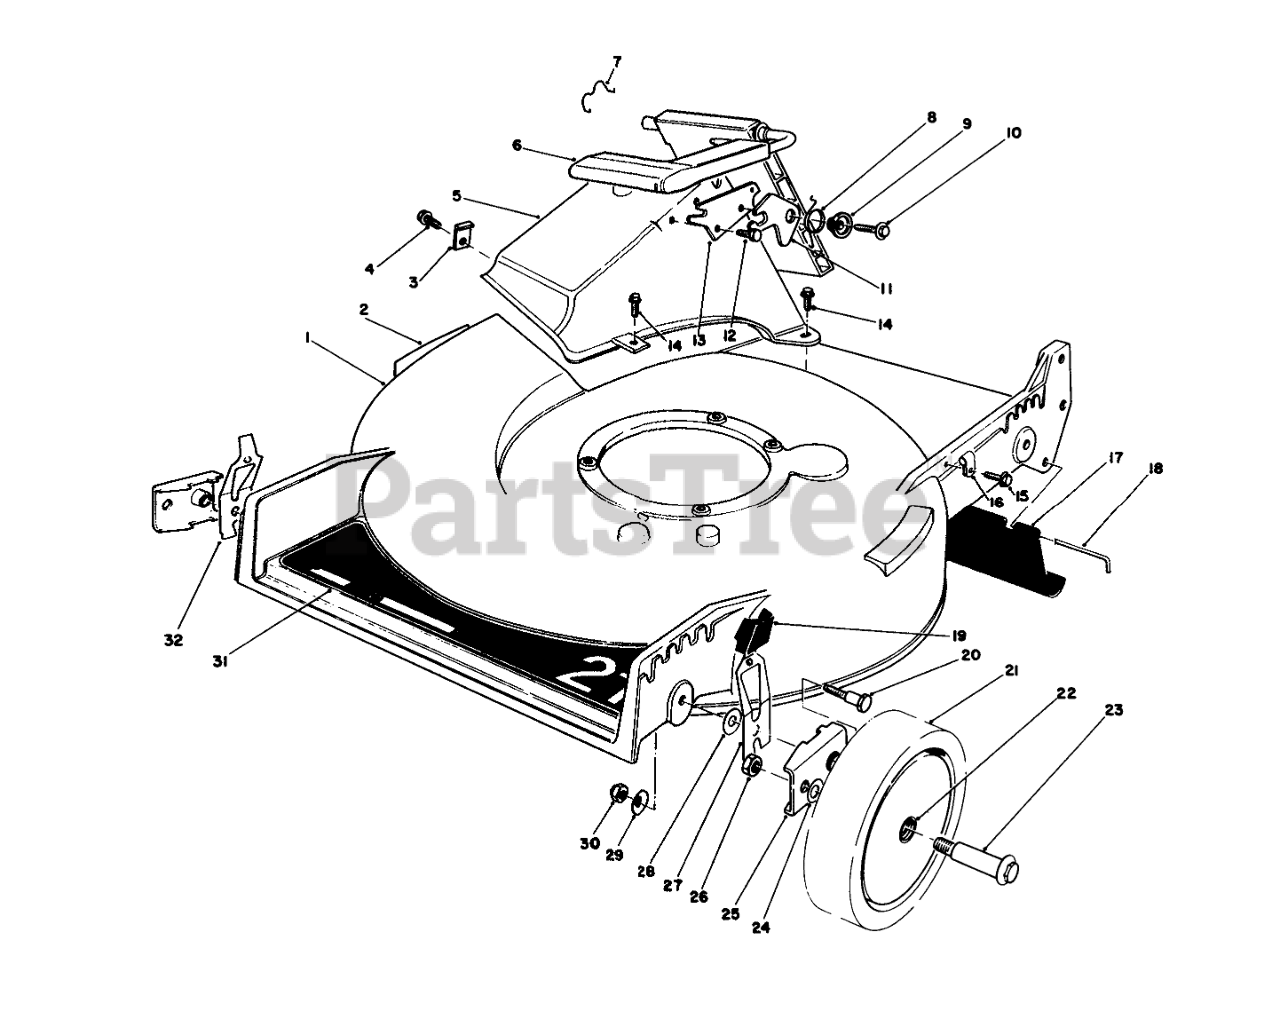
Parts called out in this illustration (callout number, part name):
1	21HP RB-SUZ HSG/DECAL
2	DECAL-DANGER
3	TUNNEL CLIP
4	SCREW
5	Tunnel Discharge
6	Discharge Door Assembly
7	DOOR RET SPRING
8	TORSION SPRING
9	DOOR SPACER
10	SCREW-HWH
11	SAFETY LATCH
12	SCREW-PLASTITE
13	DOOR LATCH PLATE
14	SCREW-HWH
15	SCREW
16	CLAMP-CABLE
17	SHIELD-TRAILING
18	ROD-SHIELD
19	KNOB-ARM
20	PIVOT SCREW
21	Wheel & Tire Assembly (Incl. Ref. #22)
22	BUSHING
23	BOLT-WHEEL
24	WASHER
25	HP PIVOT ARM ASM
26	Nut
27	L. HP SPRING ARM ASM
28	WASHER-PIVOT
29	WASHER-BELLEVILLE
30	NUT-LOCK, NI
31	DECK DECAL
32	R HP SPRING ARM ASM
